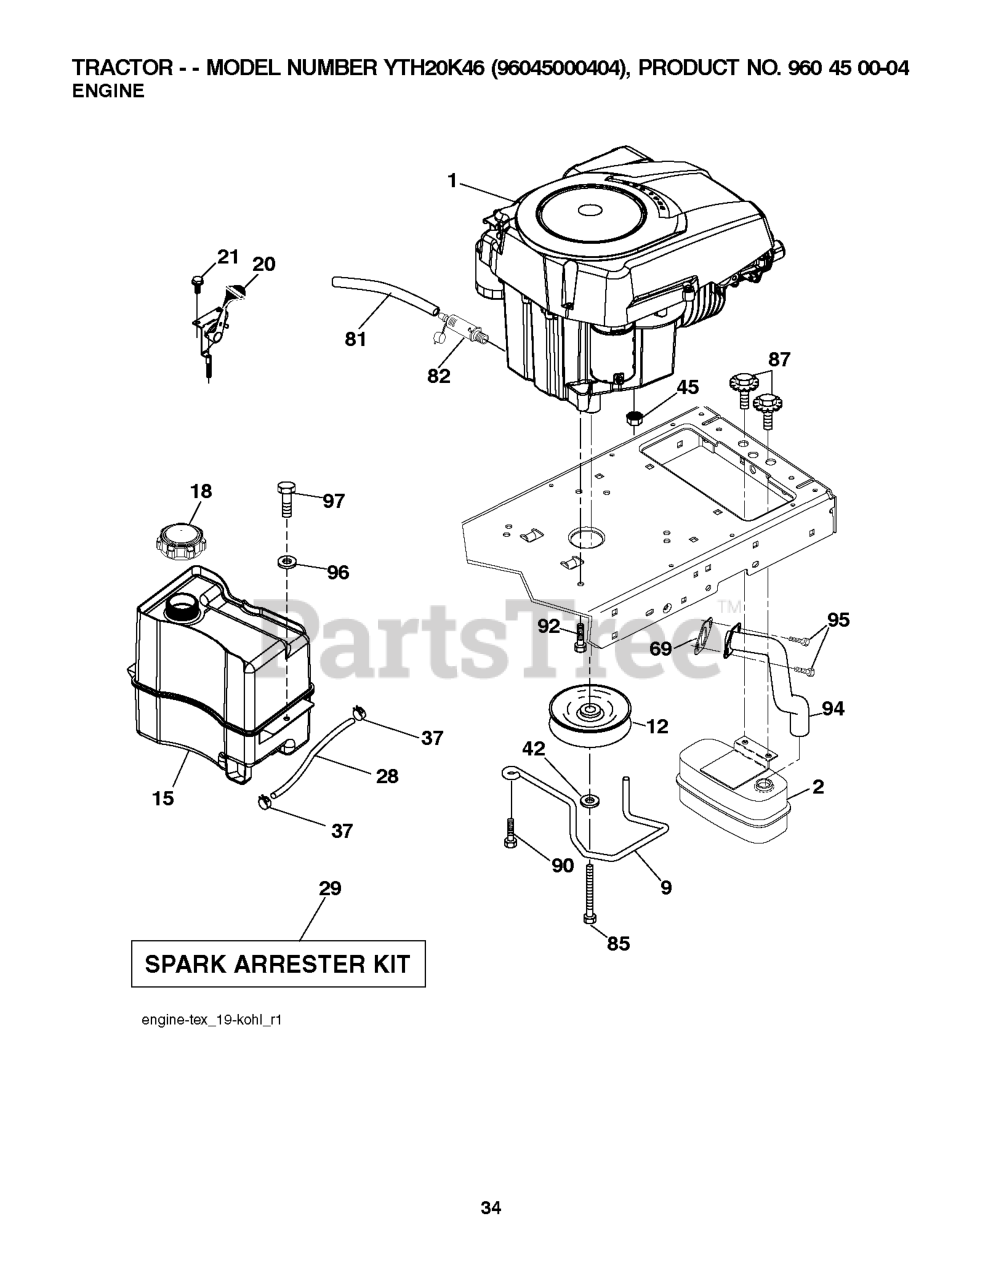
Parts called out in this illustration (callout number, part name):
2	MUFFLER.SINGLE.CYL.KOHL/B&S
9	KEEPER.BELT.ENGINE.3.25 (3 2)
12	PULLEY.ENGINE.5.0.PD
15	TANK.ASM.FUEL.FR.2.5GA.
18	FUEL CAP
20	CONTROL.TH/CK.COBRA.KO
21	SCREW
28	LINE.FUEL.20"FRONT.EMI
29	KIT.SPARK ARRESTOR 794945 B&S
37	HOSE CLAMP
42	LOCKWASHER
45	NUT
69	GASKET.EXHAUST.KOHLER
81	TUBE, DRAIN OIL ASM.
82	PLUG DRAIN OIL EASY
85	BOLT HEX 7/16-20X4-1/4"
87	BOLT 5/1618UNC X 3/4 W/ SEMS
90	SCREW 3/8-16X1
92	SCREW 3/8-16X1
94	RP.TUBE.EXHAUST.KOHL.COURAGE
95	SCREW.SOCKET HD.5/16-1
96	WASHER
97	SCREW HEXWSHR 1/4-20X3/4
